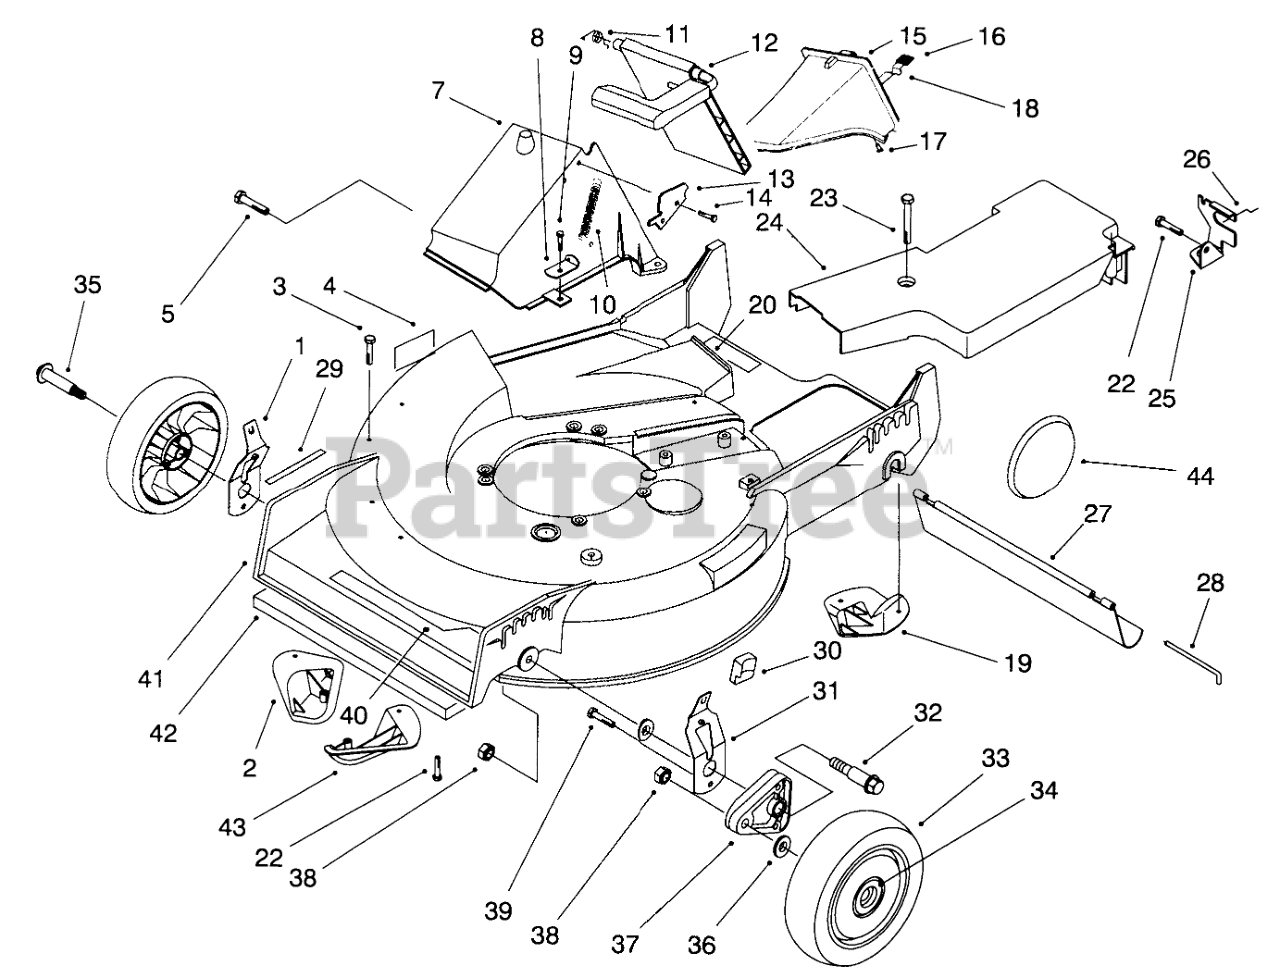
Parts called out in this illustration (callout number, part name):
1	RH SPRING ARM ASSEMBLY
2	KICKER-RH
3	SCREW-PPH
4	DECAL - DIN/DANGER
5	SCREW AND WASHER ASM
7	TUNNEL-DISCHARGE
8	BRACKET-SPRING
9	SCREW-HWH
10	SPRING-DOOR
11	RETAINER-DOOR
12	DOOR ASSEMBLY
13	DOOR LATCH PLATE
14	SCREW-PLASTITE
15	Plug Assembly (Incl. Ref. #16-18)
16	GRIP-LATCH
17	RIVET-HEAD, FLAT
18	LATCH-PLUG, DISCHARGE
19	KICKER-REAR
20	DECAL FRENCH REGUL.
22	SCREW-HWHTF
23	SCREW-HHFTF
24	BELT COVER
25	Bracket-Adj. Trac
26	RETAINER-CABLE
27	SHIELD-TRAILING
28	ROD-SHIELD
29	DECAL - HOC
30	KNOB-ARM
31	LH SPRING ARM ASSEMBLY
32	BOLT-SHOULDER
33	Wheel & Tire Assembly (Incl. Ref. #34)
34	BUSHING
35	BOLT-WHEEL
36	WASHER
37	ARM-PIVOT, FRONT
38	NUT-LOCK
39	SCREW-HWH
40	DECAL - DECK
41	Housing Assembly (Incl. Ref. #2, 3, 4, 19, 29, & 43 pg. 2) (Incl. Ref. #5 & 6 pg. 3)
42	Shield-front
43	KICKER-FRONT
44	COVER-WHEEL
